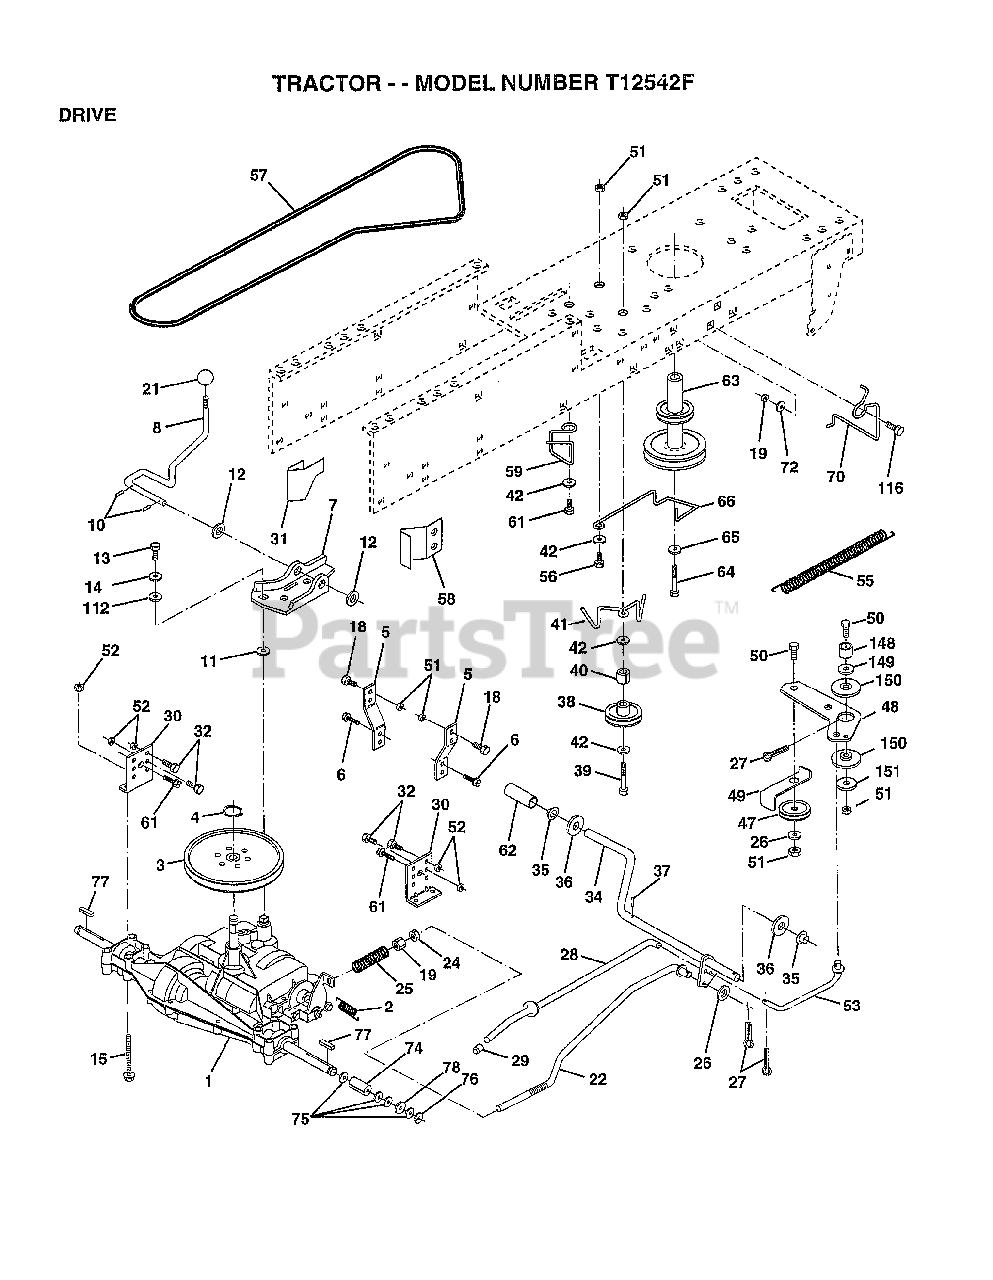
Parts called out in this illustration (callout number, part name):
2	SPRING.BRAKE.RETU
3	PULLEY TRANS
5	STRAP TORQUE
6	SCREW
7	BRKT.SADDLE.SHIFT
8	SHIFT ROD
10	PIN COTTER 1/8
11	WASH-SHFT PLT LT
12	WASHER
13	BOLT.1/4-28.W/PAT
14	LOCKWASHER
15	BOLT.HX.FLG.5/16
18	BOLT
19	NUT
21	CONTROL KNOB LT
22	BRAKE ROD
24	NUT
25	SPRING ROD LT
26	WASHER
27	COTTER PIN
28	ROD.BRAKE.PARK.LT
30	TRANSAXLE MTG BKT
31	"KEEPER,BELT LH T"
32	BOLT
34	SHAFT ASM-PEDAL F
35	NYLON BEARING
36	WASHER LT
38	PULLEY.IDLER.FLAT
39	BOLT
40	SPACER T
42	WASHER
48	BELLCRANK.CLUTCH
49	RETAIN BELT
53	"LINK, CLUTCH T"
55	"SPRING, RETURN LT"
58	"KEEPER,BELT RH T"
61	SCREW
62	PEDAL COVER T
63	PULLEY.ENGINE
64	BOLT
65	LOCKWASHER
66	KEEPER-BELT
72	WASHER
74	SPACER LT
75	WASHER
76	E-RING LT
77	SQUARE KEY
78	WASHER
112	WASHER LT
113	"STRAP,TORQUE"
116	BOLT RDHD 3/8-16
149	SPACER RETAINER
150	BUSHING.NYLON
151	WASHER
